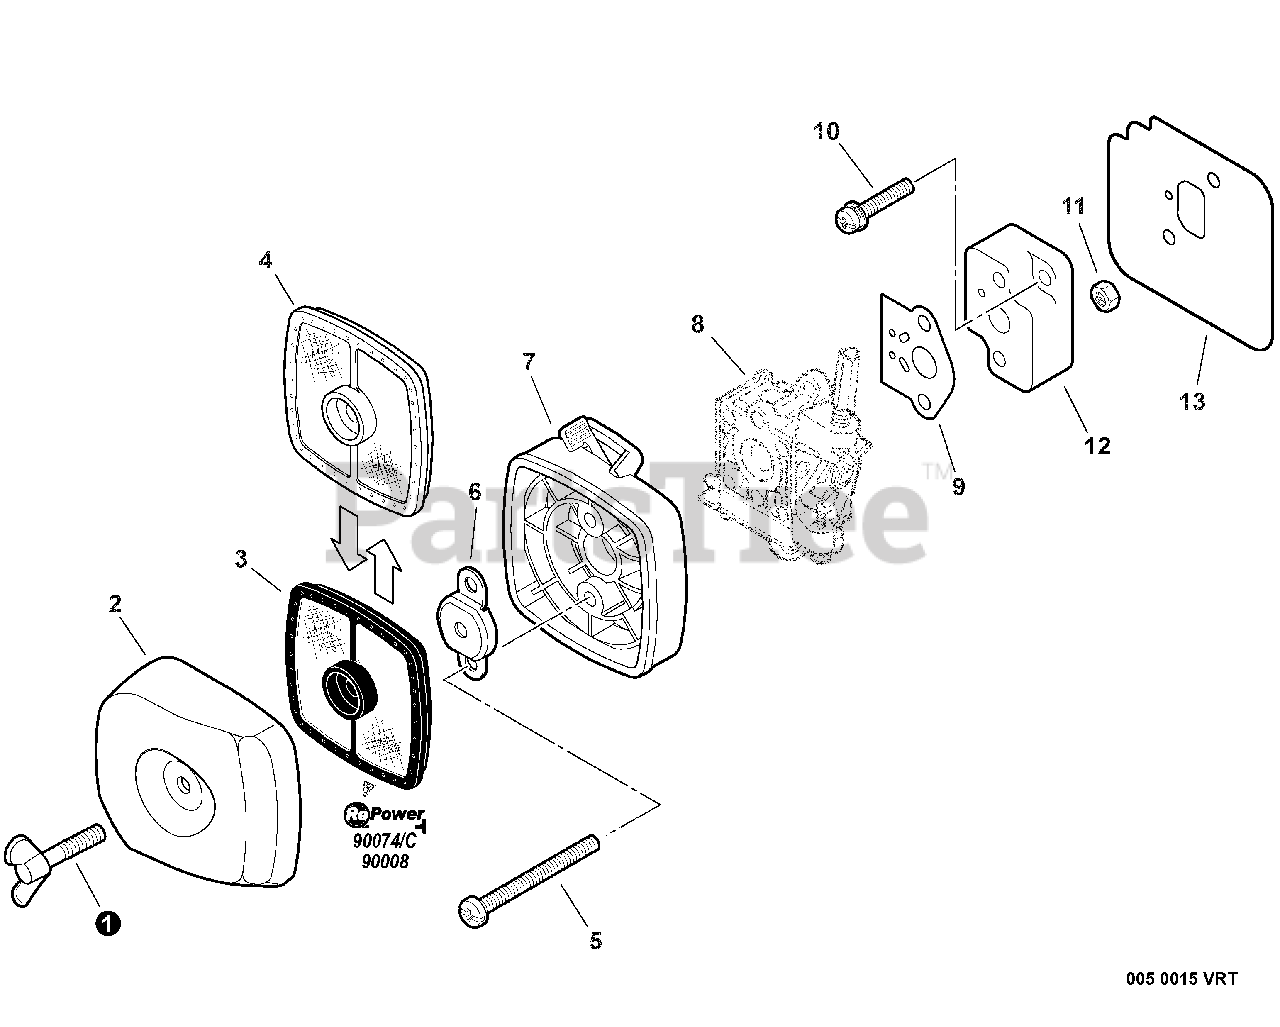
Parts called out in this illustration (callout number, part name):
1	THUMBSCREW
2	COVER, AIR FILTER - GRAY
2	COVER, AIR FILTER - BLACK
3	FILTER, AIR - DOUBLE LAYER
4	FILTER, AIR - SINGLE LAYER
5	SCREW - 5X65
6	PLATE, PREVENT
7	CASE, AIR FILTER - GRAY
7	CASE, AIR FILTER - BLACK
8	CARBURETOR
9	GASKET, INTAKE
10	SCREW - 5X22
12	INSULATOR, INTAKE
13	GASKET, INTAKE
14	RePower TUNE-UP KIT
15	RePower FILTER KIT
